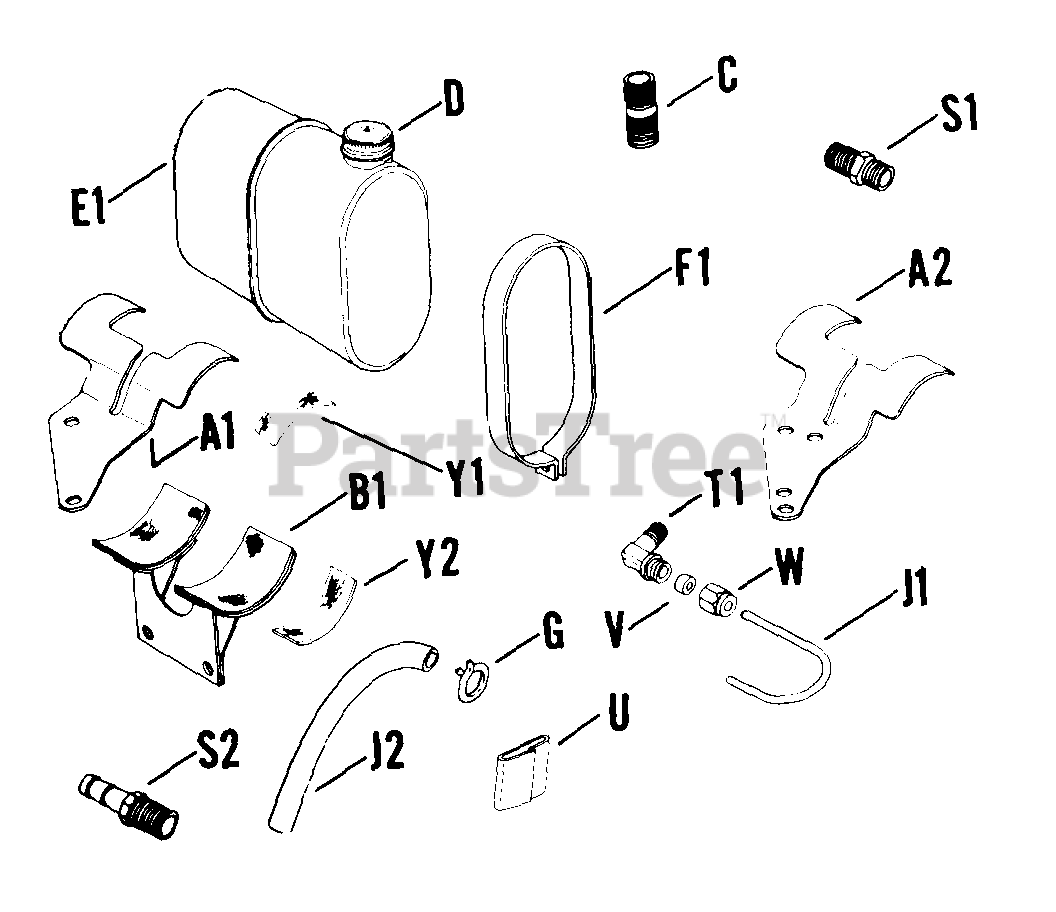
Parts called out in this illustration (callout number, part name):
A2	BRACKET - USE 47 217 10
B1	BRACKET - USE 47 217 11
D	CAP USE 236655-S
E1	TANK, FUEL USE 47 065 10-S
F1	STRAP-DISCONTINUED
G	HOSE CLAMP USE X-426-9-S
J2	LINE - USE X-767-2
